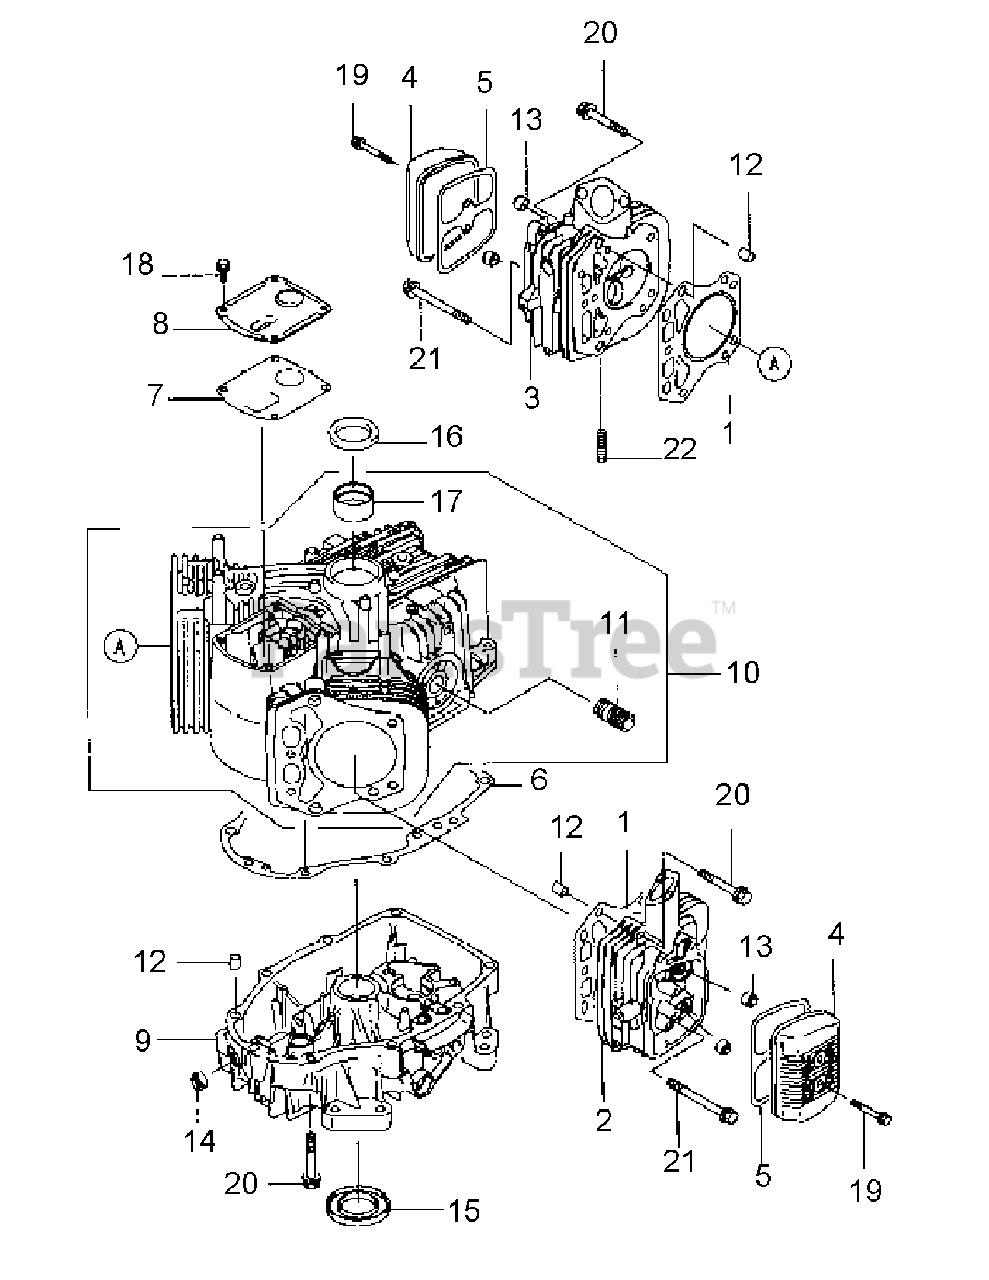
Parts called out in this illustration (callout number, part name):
2	HEAD-COMP-CYLINDER, #2
3	HEAD-COMP-CYLINDER, #1
5	GASKET, ROCKER CASE
7	GASKET, BREATHER
9	COVER-CRANKCASE
10	CRANKCASE-COMP
13	SEAL-OIL,RVC2 6X11X10.2
14	SEAL-OIL,SO 8X14X5 HS
15	SEAL-OIL,SD 35X62X8 L HS
16	SEAL-OIL, SD 35X48X8 R HS
17	BUSHING
18	BOLT-FLANGED
19	BOLT-FLANGED
20	BOLT-FLANGED
21	BOLT-FLANGED
